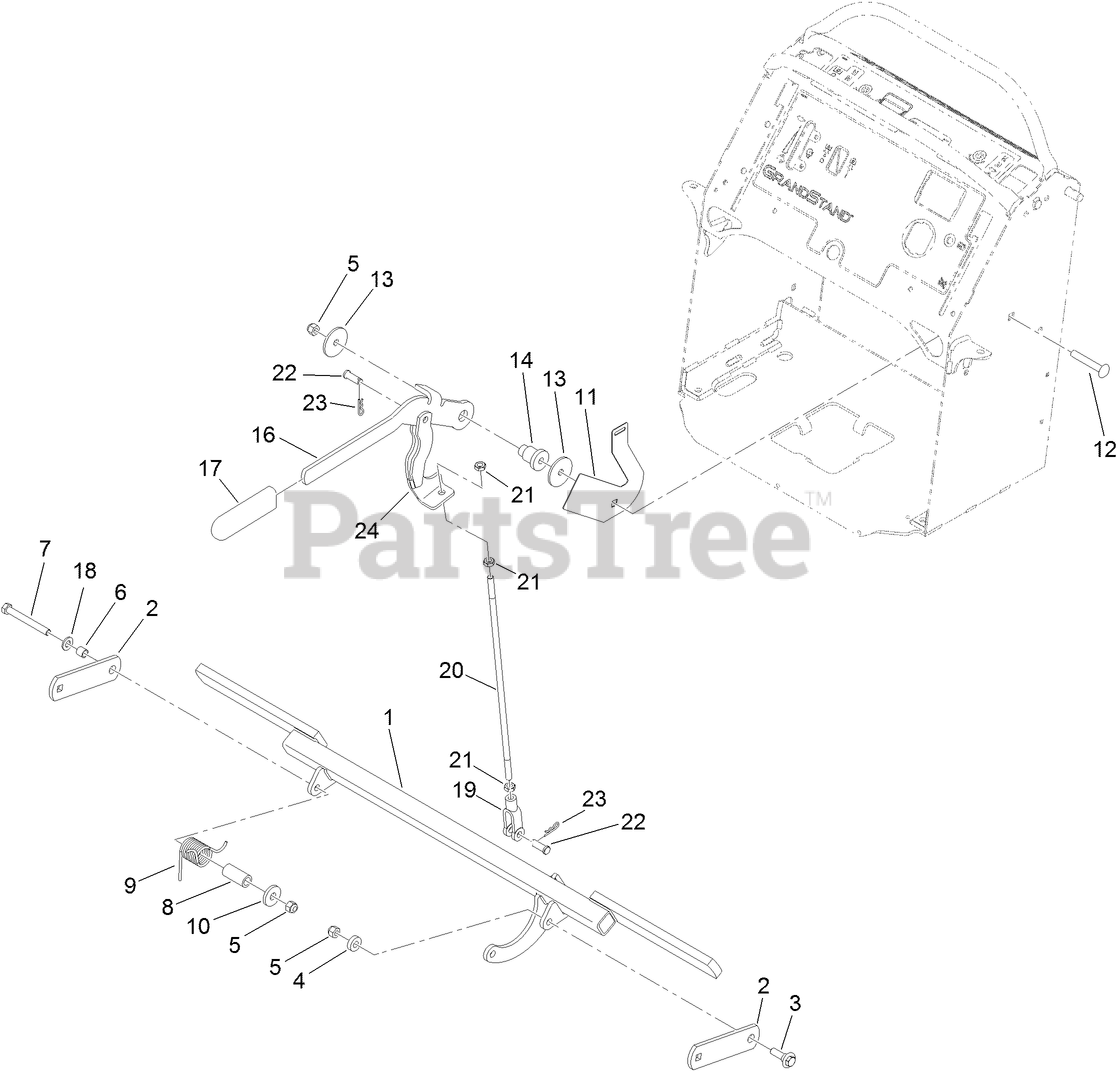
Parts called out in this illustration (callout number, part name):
1	BAR-BRAKE
2	SUPPORT-BRAKE
3	SCREW-SHOULDER, HWH
4	SPACER
5	NUT-LOCK, NI
6	SPACER
7	SCREW-HH
8	SPACER
9	SPRING-TORSION
10	WASHER
11	PLATE-SWITCH, BRAKE
12	SCREW-CARR
13	WASHER-REBOUND
14	MOUNT-PULLEY
16	LEVER-BRAKE
17	GRIP-LEVER
18	WASHER-FLAT
19	YOKE-LINKAGE, BRAKE
20	ROD-BRAKE
21	NUT-HJ
22	PIN-CLEVIS
23	PIN-COTTER
24	ARM-BRAKE
